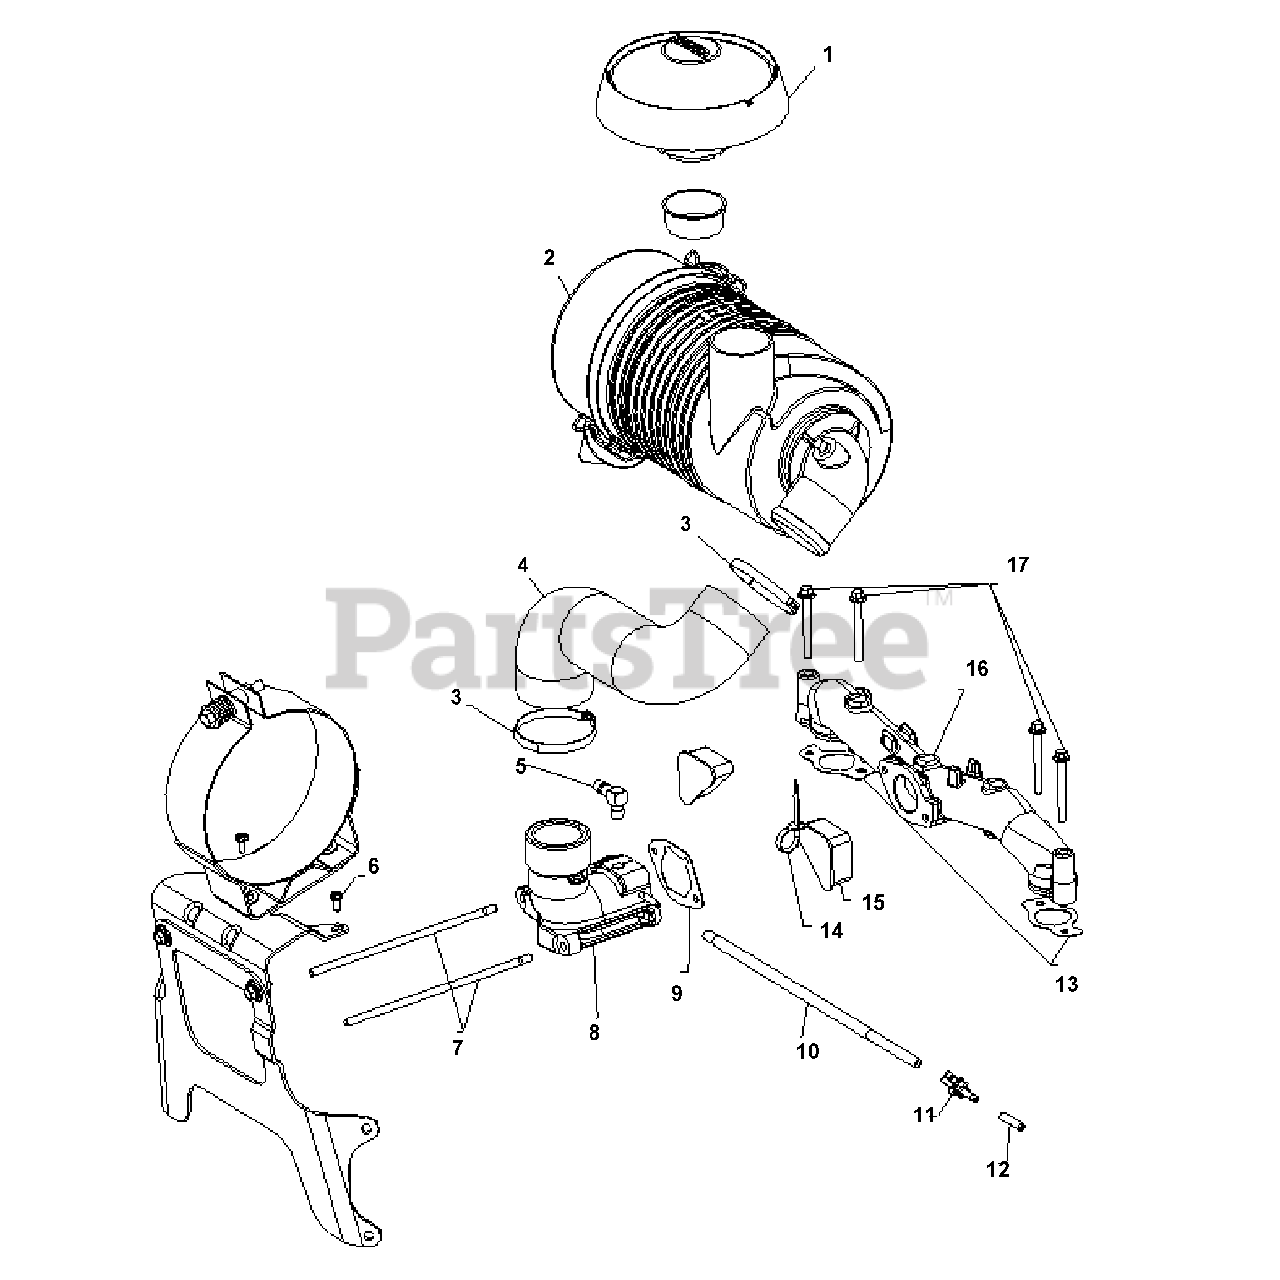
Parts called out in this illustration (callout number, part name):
4	Air Cleaner Hose
5	Hose Connecter
6	Screw, #8-18 x 1/2
7	Stude, M6 x 1.0 x 180
9	Air Cleaner Base Gasket
10	Evaporative Hose
11	Evaporative Connector
13	Intake Manifold Gasket
15	Blower Housing Cover
16	Intake Manifold
17	Screw, M6 x 1.0 x 55
